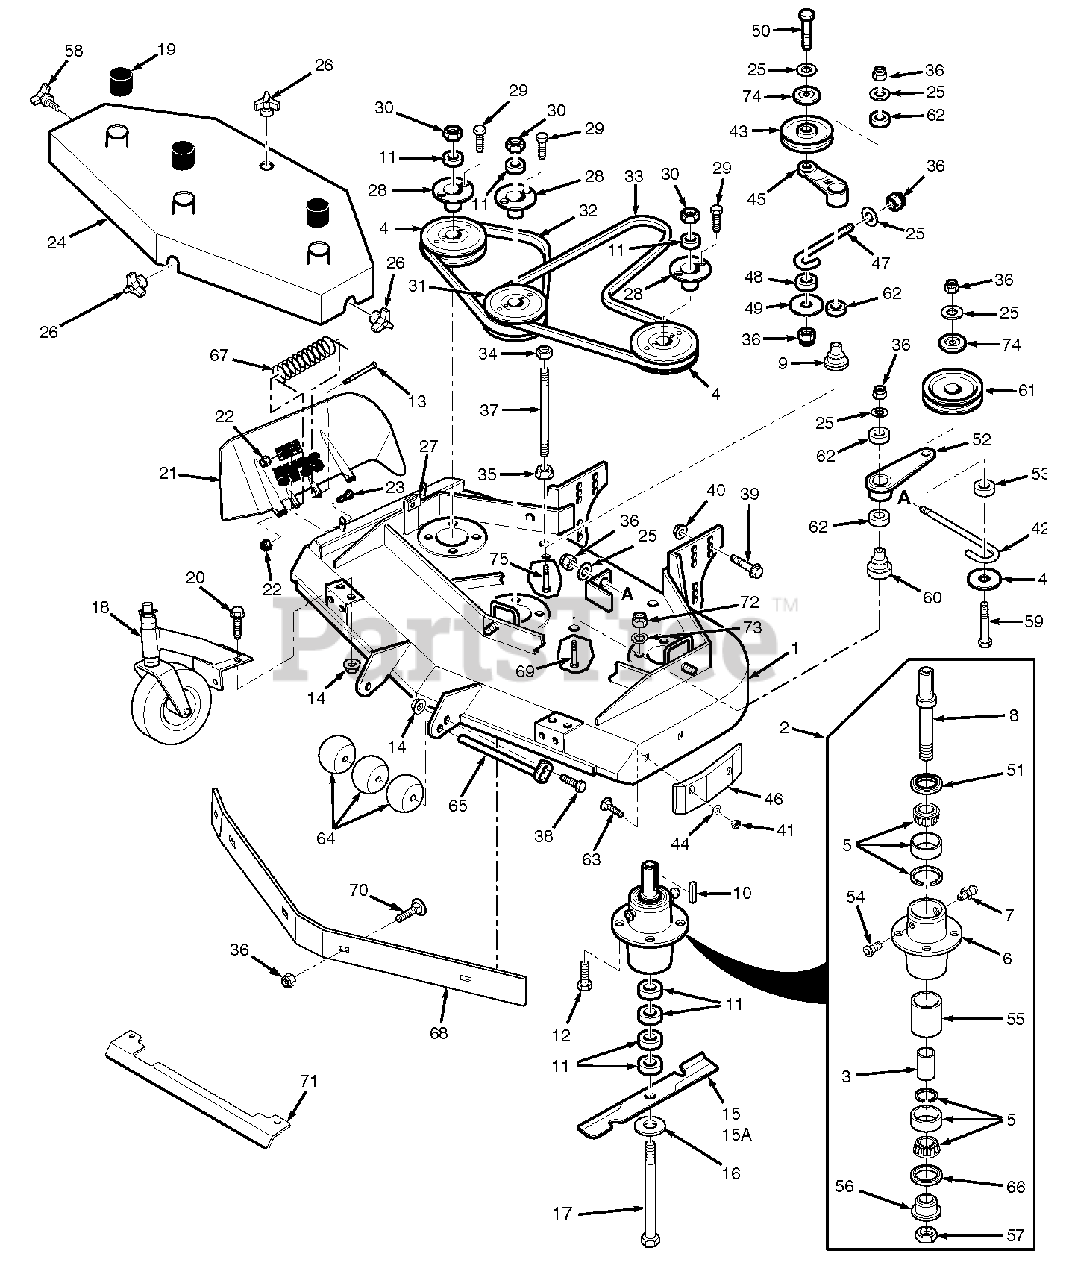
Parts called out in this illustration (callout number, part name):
1	Cutter Deck w/Decals
2	Spindle Assembly
3	Spacer, Inside
4	Pulley
5	Tapered Bearing
6	Spindle Housing
7	Grease Fitting Str. 5/16"
8	Spindle Shaft
9	Idler Pivot
10	Key, 1/4 x 1/4 x 2"
11	Spacer, Cutter Blade - Small
12	Bolt, 5/16-18 x 1-1/2" Hex Head Gr. 8
13	Bolt, 5/16-18 x 4-3/4" Hex Head
14	Serr. Flange Nut, 5/16-18
15	Cutter Blade 16-1/2"
15	Cutter Blade 18"
15A	Cutter Blade 16-1/2 Hi-Lift
15A	Cutter Blade 18 Hi-Lift
16	Flatwasher,5/8" (.688 x 1.75 x .134)
16	Hex Head Bolt, 5/8-11 x 9-1/2"
17	Caster Assembly
17	Cap, Spindle
18	Capscrew, 5/16-18 x 3/4"
19	Discharge Chute 48V
21	Discharge Chute 52V
21	Turbo Baffle, 52V
22	Nut, 5/16-18 Elastic Elastic Stop
23	Bolt, 5/16-18 x 1-1/2" Hex Head
24	Belt Cover (Incl. decals)
25	Flat Washer, 3/8" Special
26	Wing Nut, 3/8-16 (Large)
27	U-Nut, 3/8-16
28	Tapered Hub
29	Bolt, 1/4-20 x 1" Hex Head
30	Nut, 5/8-11 Hex
31	Pulley, Double
32	Belt, RH Blade Drive
33	Belt, Blade Drive
34	Nut, 3/8-16, Nut Centerlock
35	Nut, 3/8-16, Serrated Flange
36	Nut, 3/8-16 Elastic Stop
37	Bolt, 5/16-18 x 1" Hex Head
38	Bolt, 5/16-18 x 1" Hex Head
39	Cpscrw, 1/2-13 x 1" Ser.Flg. HH
40	Nut, 1/2-13 Flange El. Stop
41	Hex Nut, 5/16-18 Center Locknut
42	J-Hook, 48V
42	J-Hook, 52V
43	Idler Pulley, "V" Groove
44	Flatwasher, 5/16"
45	Idler Arm Assy.
46	Pad, Deck Wear
47	J-Rod, Idler Pulley
48	Spacer, J-Rod
49	Washer, 3/8 x 1-1/2 x 16 ga.
50	Bolt, 3/8-16 x 2-1/2" Hex Head
51	Seal, Cutter Spindle
52	Idler Arm Assy
53	Spacer, J-Rod
54	Reiief Fitting, Cutter Spindle
55	Spacer, Outside, Cutter Spindle
56	Spindle Bushing
57	Nut, Cutter Spindle
58	Knob, w/stud
59	Bolt, 3/8-16 x 3-3/4" Hex Head
60	Idler Pivot
61	Idler Pulley, Belt Clutch
62	Bearing
63	Bolt, Carriage 5/16-18 x 3/4"
64	Guide Roller
65	Roller Shaft
66	Seal, Cutter Spindle
67	Spring, Chute Return
68	Baffle Weldment 48V
68	Baffle Weldment 52V
69	Bolt, 3/8-16 x 3-1/4" Hex Head
70	Bolt, Carriage 3/8-16 x 1"
71	Heatshield
72	Nut, Hex Lock 5/16-18
73	Lock Washer 5/16"
74	Dust Shield
75	Bolt, 3/8-16 x 2-3/4" Hex Head
